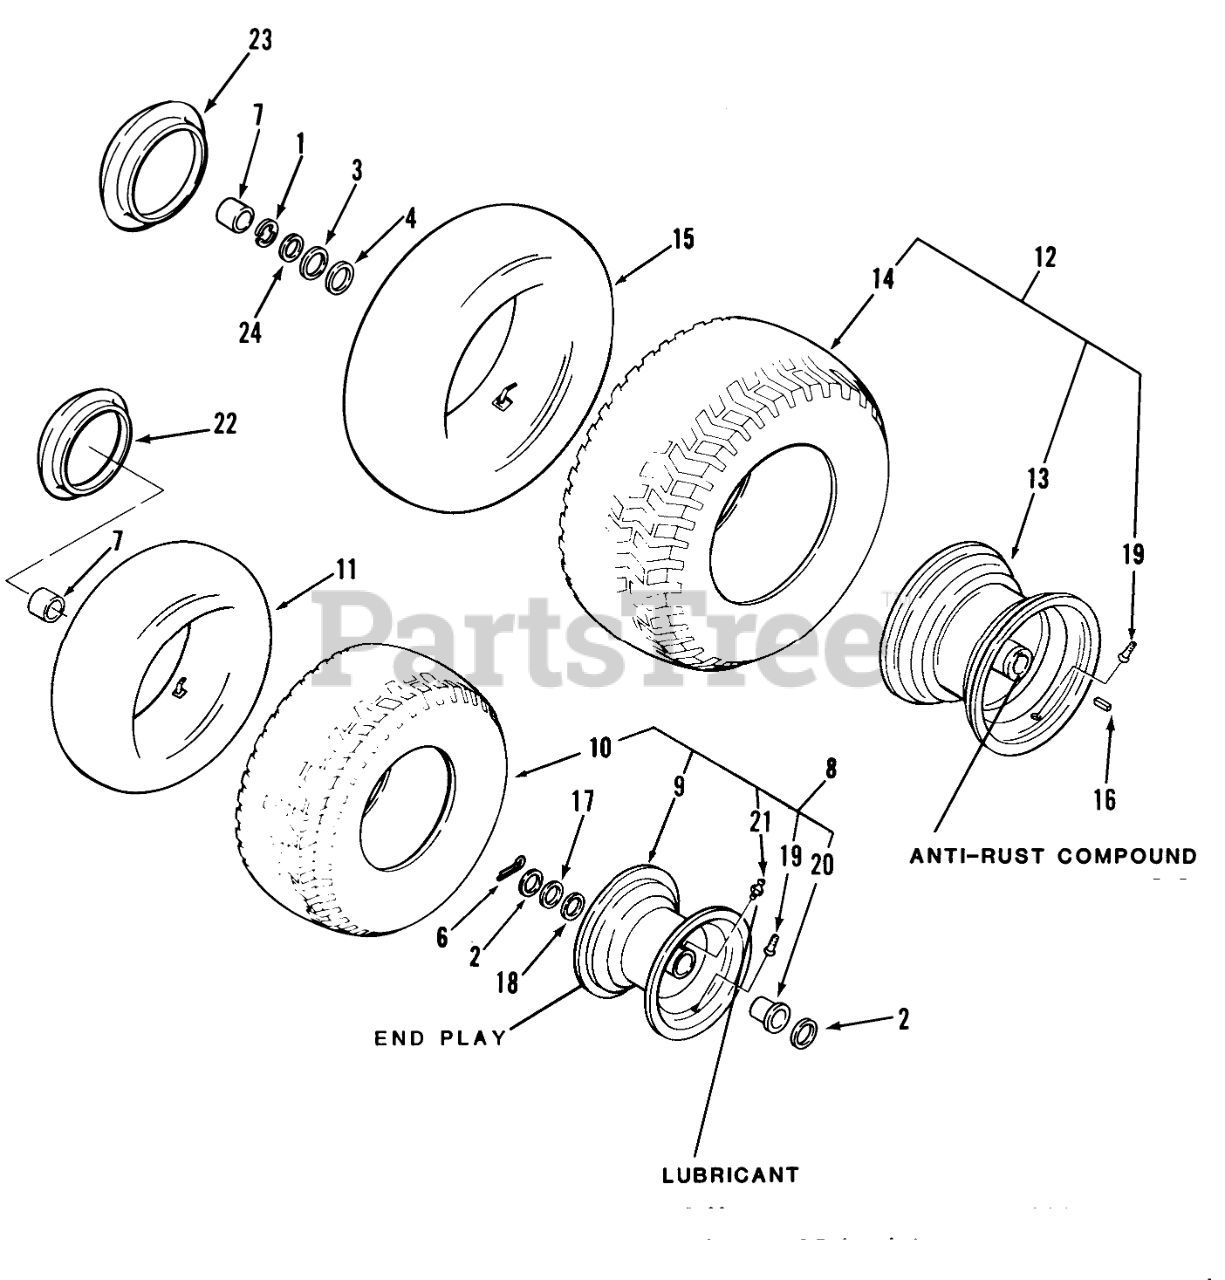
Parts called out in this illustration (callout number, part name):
1	E RING
2	WASHER-WHEEL
3	WASHER-SHIM
3	Washer
4	WASHER
6	COTTER PIN-4
7	HUB CAP-FLAT BLACK
8	Assy-Wheel & Tire Front
9	Front Wheel (includes Rim, items 19, 20 & 21)
10	TIRE15 X 6.00-6
12	Assy-Wheel & Tire-Rear 252-H
12	Assy-Wheel & Tire-Rear 257-H
13	Rear Wheel (Complete)
14	TIRE-22 X 8.00-12
14	TIRE 22 X 9.00-12
15	INNER TUBE
15	TUBE-INNER
16	Key
17	WASHER
18	WASHER-SHIM
19	VALVE
20	BEARING-WHEEL
21	ZERK-GREASE
22	6"-HUB CAP LOGO
23	12"-HUB CAP LOGO
24	Washer
